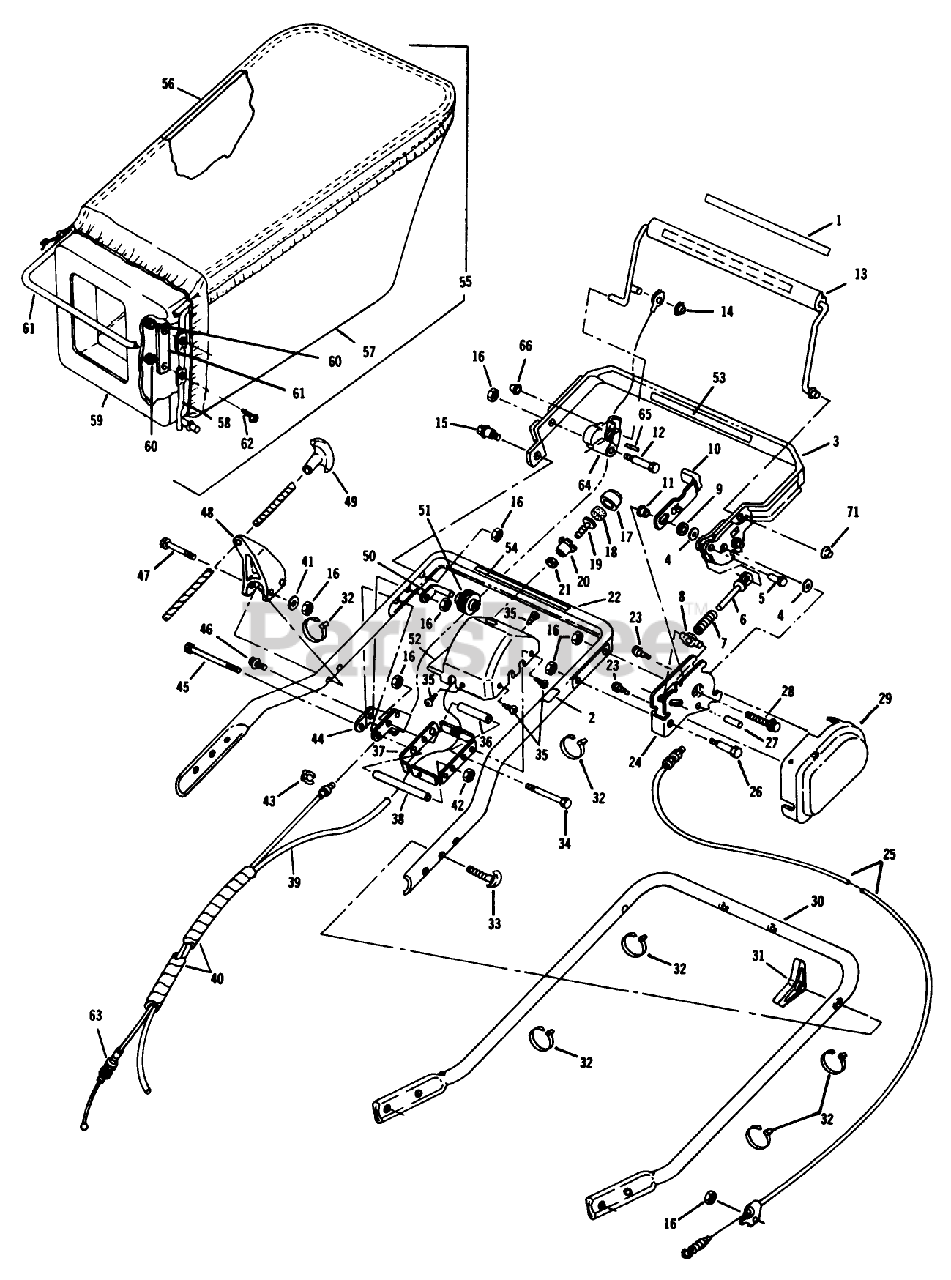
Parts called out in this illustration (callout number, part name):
9	WASHER M
14	NUT ACORN
15	BOLT
16	LOCKNUT E
18	FILTER S
21	LOCKNUT S
25	CABLE ASM
30	HANDLE AY-LOWER (12)
31	NUT-WING
33	BOLT QUALITY
35	SCREW F
36	SPACER
38	Spacer
41	WASHER
43	RET. RING
45	BOLT-CONSOLE
49	HANDLE,STARTER
56	HANGER BAG TROX
59	BAG ADAPTOR PL
60	LOCKNUT E
63	CONTROL CABLE
